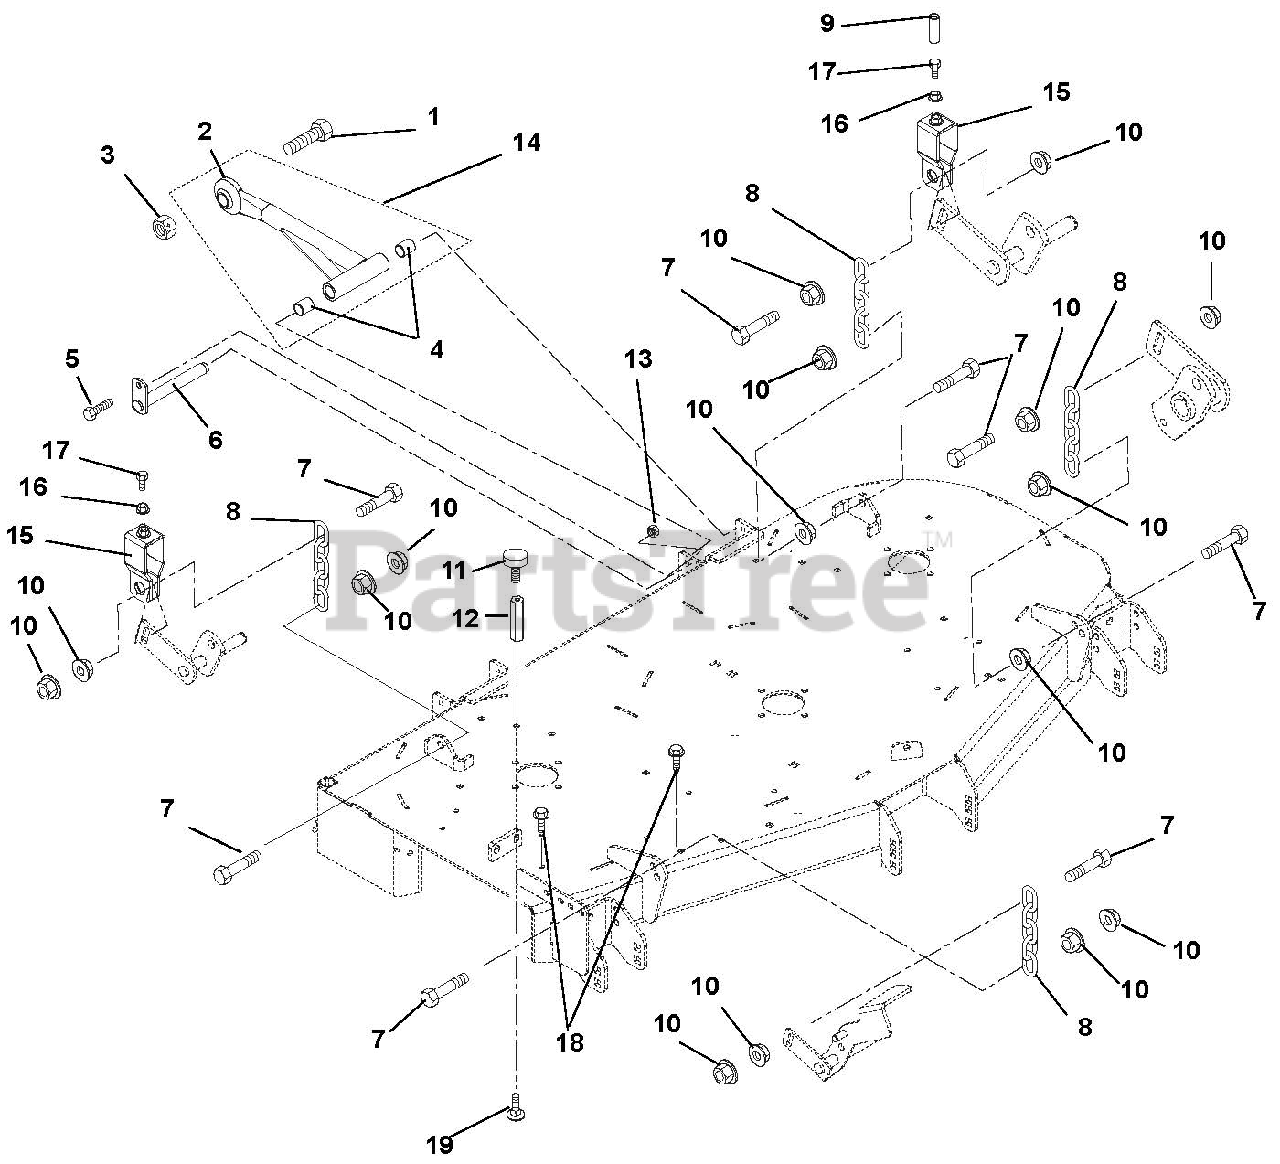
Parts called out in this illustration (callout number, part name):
1	Bolt, Hex .875-9 x 2.75 Grade 5
2	Mower Mounting Arm Weldment
3	Nut, Locking Center .875-9
4	Bearing, .75 x .875 x 1.00
5	Bolt, Hex .38-16 x 1.00 Grade 5
6	Weldment, Mower Mounting Pin
7	Bolt, Hex M12-1.75 x 50 Grade 5
8	Chain, Link
9	Cap, Vinyl .50 ID x 1.50LG x .055
10	Nut, Spin Lock Flange M12-1.75
11	Bumper, Rubber
12	Nut, Coupling .31-18 x 3.00
13	Nut, .38-16 Nyloc Flange
14	Assembly, Mower Mounting Arm
15	Bracket, Deck Leveling
16	Nut, Jam .312-18
17	Bolt, Full Thread Hex .312-18 x 2.00
18	Screw, Tapping Hex Washer Head Thread .38-16 x .50
19	eck .31-18 x .75
